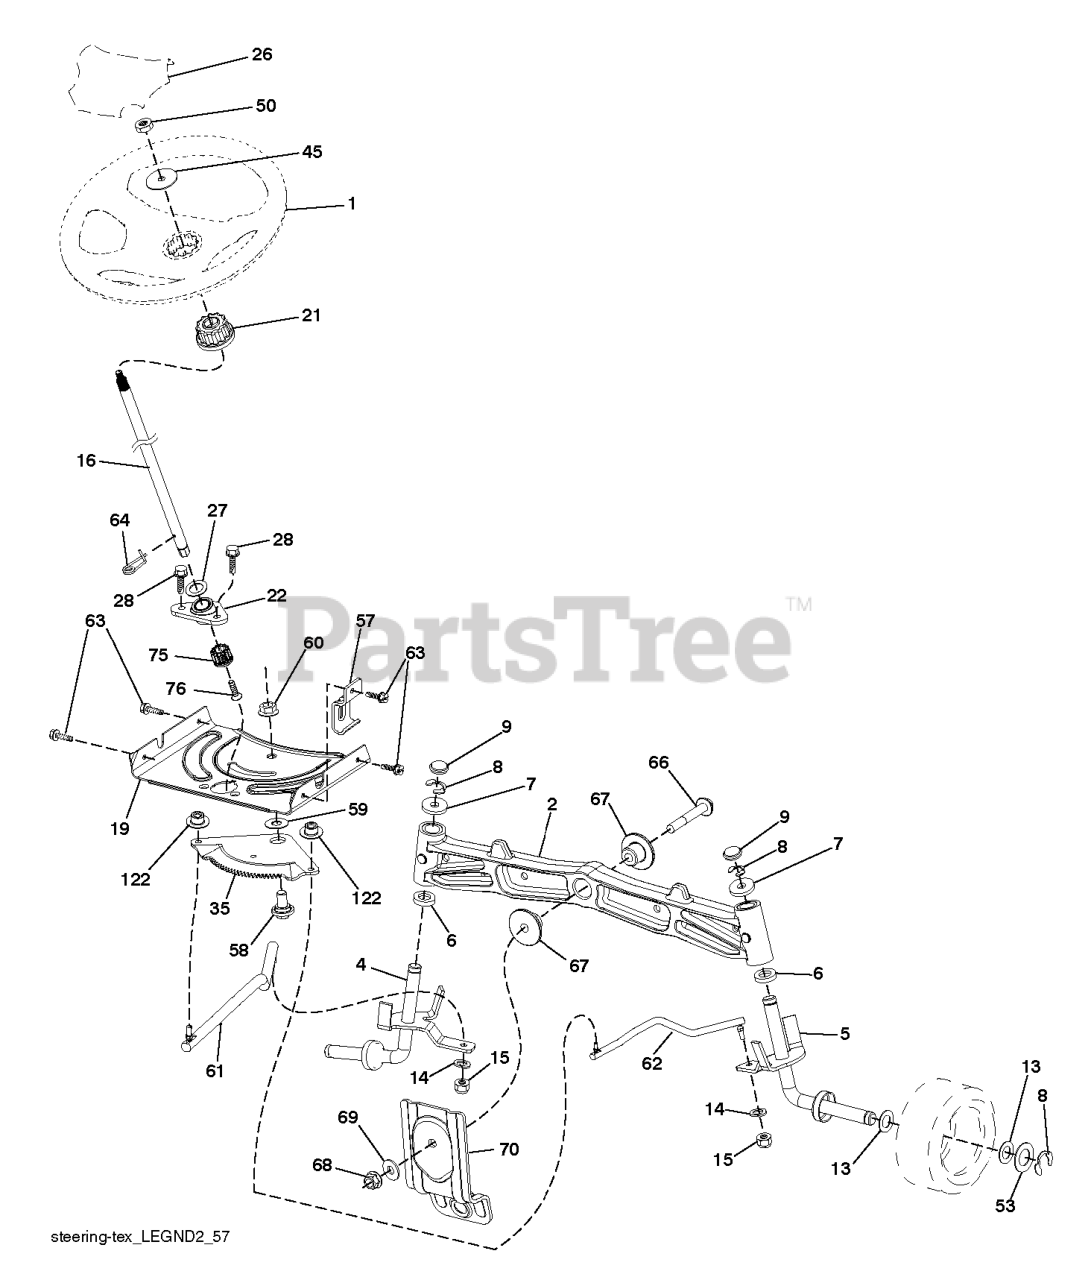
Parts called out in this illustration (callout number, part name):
1	Service Kit
1	WHEEL.STEER.HUSQ.SR.498.OVMLD
2	AXLE.CAST.IRON
4	SPINDLE.WELDED.LH.15"TEX
5	SPINDLE.WELDED.RH.15"T
6	WASHER THRUST
9	CAP.SPINDLE.BLACK
15	NUT CROWNLOCK 3/8-24
16	SHAFT.STEER.2HIGH.SPLND.PLATED
16	SHAFT, STEERING
16	KIT.SRVC.STEERINGSHAFT.2HISHFT
19	PLATE.STEER.DDL.NLT/NG
21	ADAPTER, WHEEL STNG..
21	ADAPTER.WHEEL.STEER.SPLND.ALUM
22	BEARING.SHAFT.STEER.LOWER.625
22	STEERING.SUPT.LOWER.
26	INSERT.CAP.WHL.STRG.HUSQ.PREM
26	Steering
27	WASHER LT
27	Washers
27	WASHER
28	SCREW, 3/8-16X3/4
35	GEAR.SECTOR.PLATE.DDL.
45	WASHER 9/16"ID, 2 3/8"OD
45	WASHER.3/8ID.2-3/8OD.12GA.PLTD
50	NUT.HEX.1/2-20
50	NUT.HEX.FLANGE.3/8-16.LOCKNUT
50	NUT LOCK FLG 3/8-16 UNC
53	WASHER.HARDENED
57	BRKT.UPSTOP.GT/LT.TEX
58	BOLT.SHOULDER.SECTOR.P
59	WASHER.THURST.SECTOR.S
60	NUT FLANGE LOCK 5/8-11
61	DRAGLINK.LH.BALLSTUD.D
62	DRAGLINK.RH.BALLSTUD.D
63	SCREW
64	RETAINER.CLIP.SPRING.S
66	BOLT HEX FGHD 7/16-14 X 3 SERR
67	BUSHING.PM.FRONT AXLE
68	NUT.LOCK.FLANGE.7/16
69	WASHER.1.5X.505X.118
70	BRACKET.FRT.DECK.SUSP.RR.MT431
75	PINION.ZINC PLATED
76	SCREW HEAD SOCKET LRVB
122	CAP.GEAR.SECTOR.TEX
